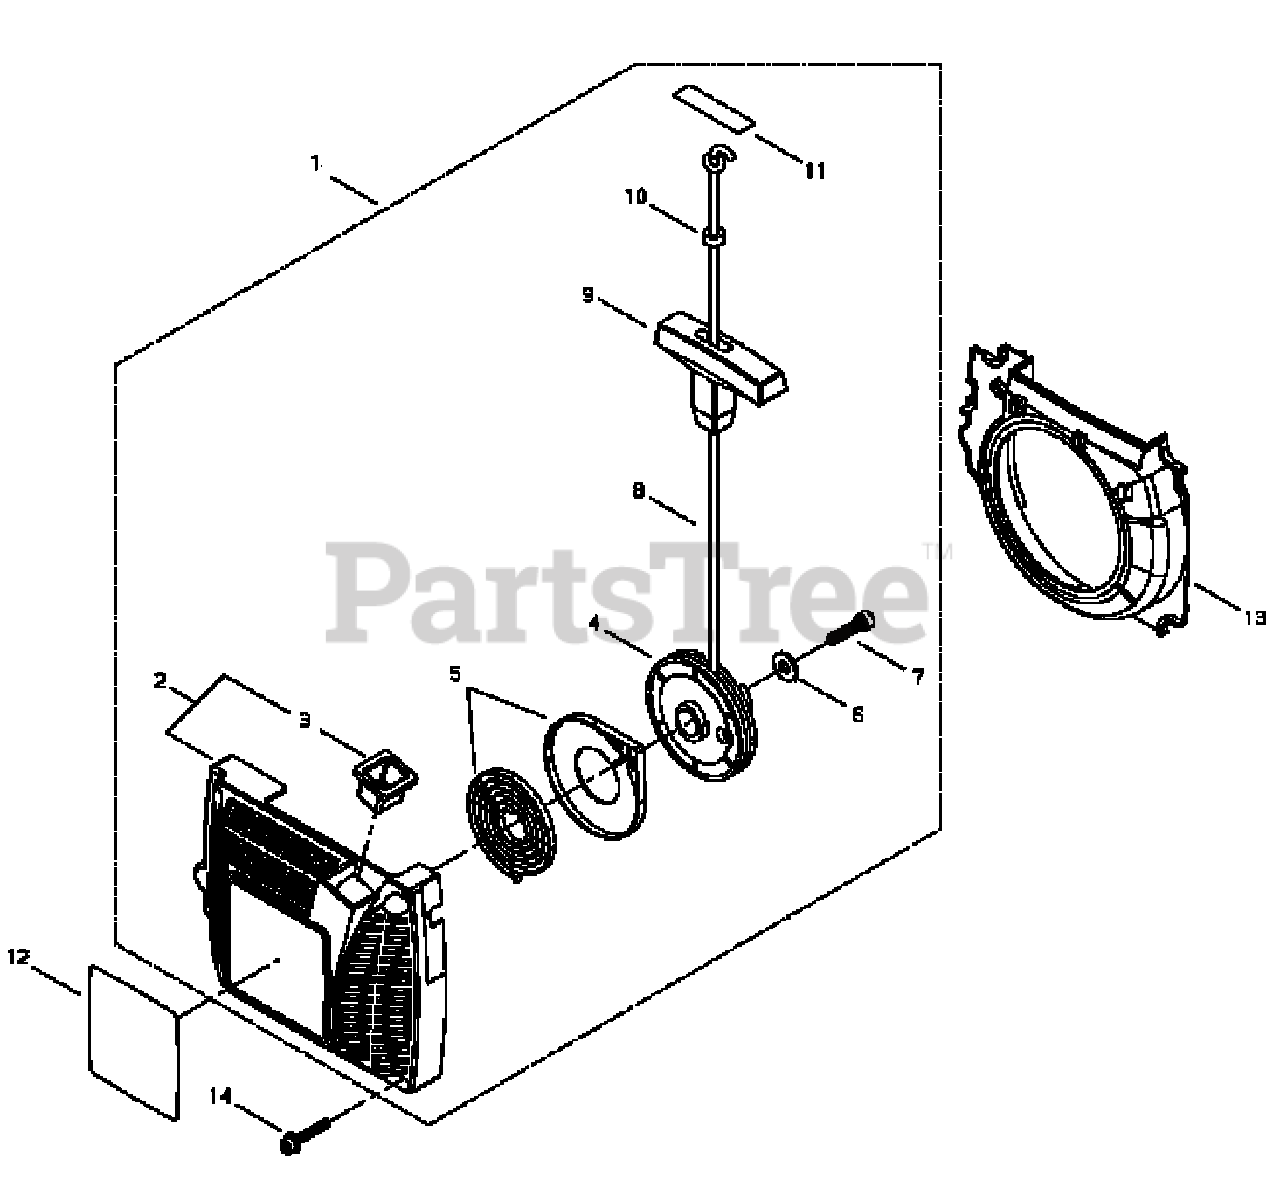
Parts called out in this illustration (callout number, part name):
1	STARTER ASSY
2	CASE, STARTER
3	GUIDE, ROPE
4	REEL, ROPE
5	SPRING, REWIND
6	WASHER
7	SCREW - 5X12
8	ROPE, STARTER
9	GRIP, STARTER
10	STOPPER KNOB
11	TAPE, ADHESIVE
12	LABEL - TRADE
13	PLATE, AIR
14	SCREW - 4X16
